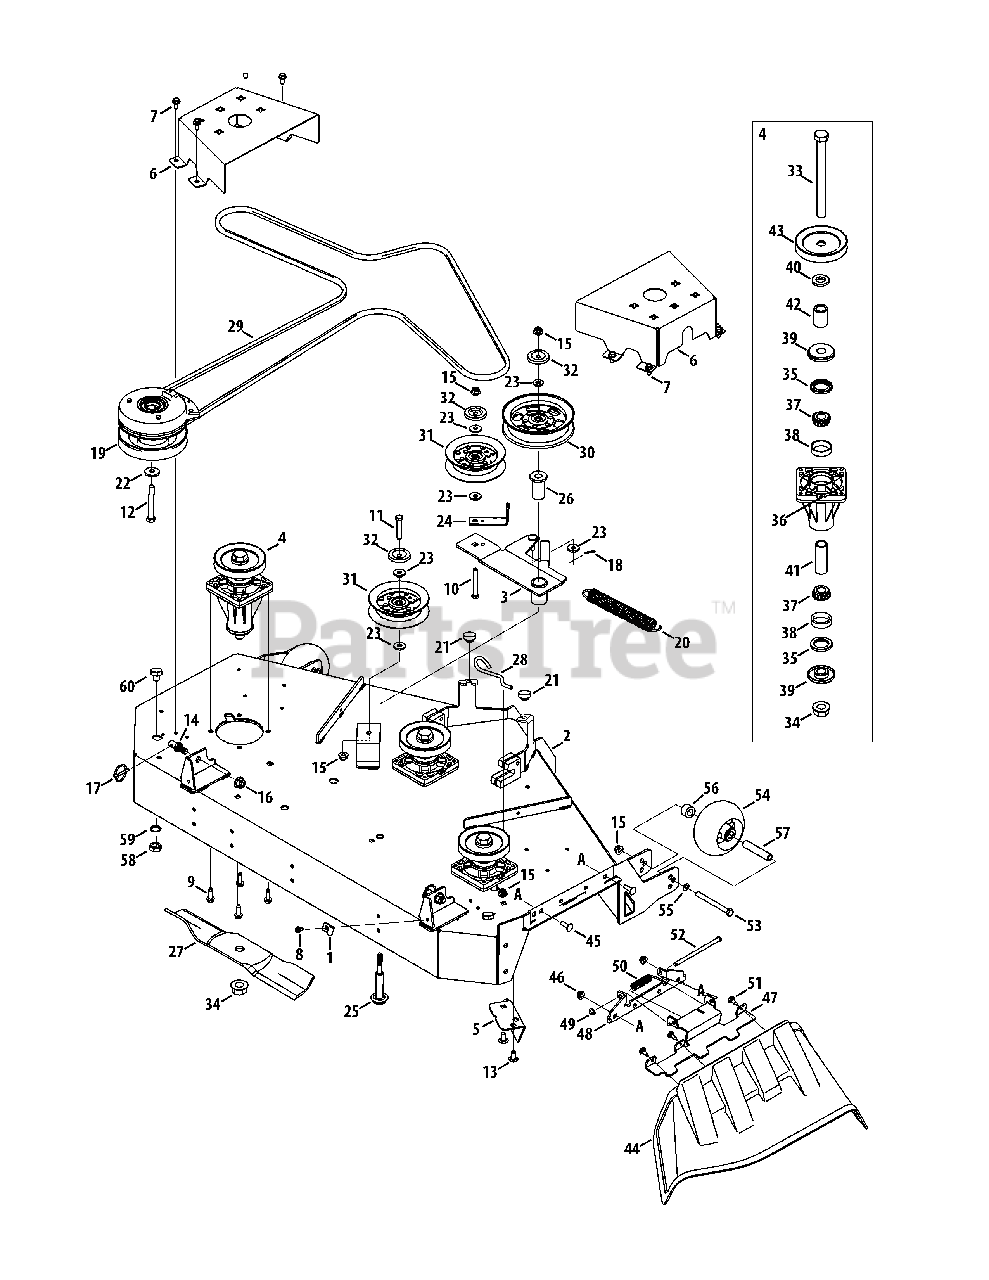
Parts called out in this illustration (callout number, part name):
1	Bracket, Hook Retainer
2	48" Deck FAB
3	Deck Idler Assembly
4	Spindle Assembly
6	Belt Cover
7	Hex Washer Screw, 5/16-18 x .750
8	Hex Washer Screw, 1/4-20 x .500
9	Hex Washer Screw, 5/16-18 x 1.250
10	Hex Cap Screw, 3/8-16 x 2.50
11	Hex Cap Screw, 3/8-16 x 2.00
12	Screw, 7/16-20 x 3.25
13	Carriage Screw, 3/8-16 x .75
14	Pin, Shoulder Lock, .500
15	Flange Lock Nut, 3/8-16
16	Flange Lock Nut, 1/2-13
17	Pin, Lynch x .1875
18	Cotter Pin 3/32" Dia. x .75 Lg.
19	Electric PTO Clutch
20	Extension Spring, 1.25 OD x 1.751
21	Rubber Bumper, 1.00 x .313
22	Flat Washer, .450 x 1.25 x .164
23	Flat Washer, .406 x .875 x .105
24	Belt Guard Bracket
25	Shoulder Boult, .625 x 2.12, 3/8-16
26	Shoulder Spacer, 1.055 x .627 x 2.292
27	Blade, 17.00
28	Deck Spring Rod
29	V-Belt
30	Idler Pulley, 5.00 Dia.
31	Idler Pulley, 4.00 Dia
32	Pulley Cap
33	Hex Cap Screw, 3/4-16 x 8.25
34	Nut, 3/4-16, Flangelock
36	Grease Fitting
37	Cone Bearing
38	Cup Bearing
39	Spindle Spacer
40	Spacer, .812 ID x .218 LG
41	Spacer, .78 x 1.00 x 2.895
42	Spacer, .792 x 1.20 x 1.628
43	V-Type Pulley
44	Discharge Chute Assembly
45	Carriage Bolt, 5/16-18 x 1.00
46	Flange Lock Nut, 5/16-18
47	Chute Bracket
49	Push Cap
50	Torsion Spring
51	Shoulder Screw, 1/4-20
52	Chute Rod
53	Hex Cap Screw, 3/8-16 x 4.0
54	Deck Ball Wheel, 5.0
55	Flat Washer, .406 x .875 x .059
56	Shoulder Spacer, .500 x 3.09
57	Spacer, .380 x .495 x 3.450
58	Hex Nut, M-16 x 1.5
59	Lock Washer, 17 x 23.8 x 1.95
60	Plug, Screw, M16-1.5
